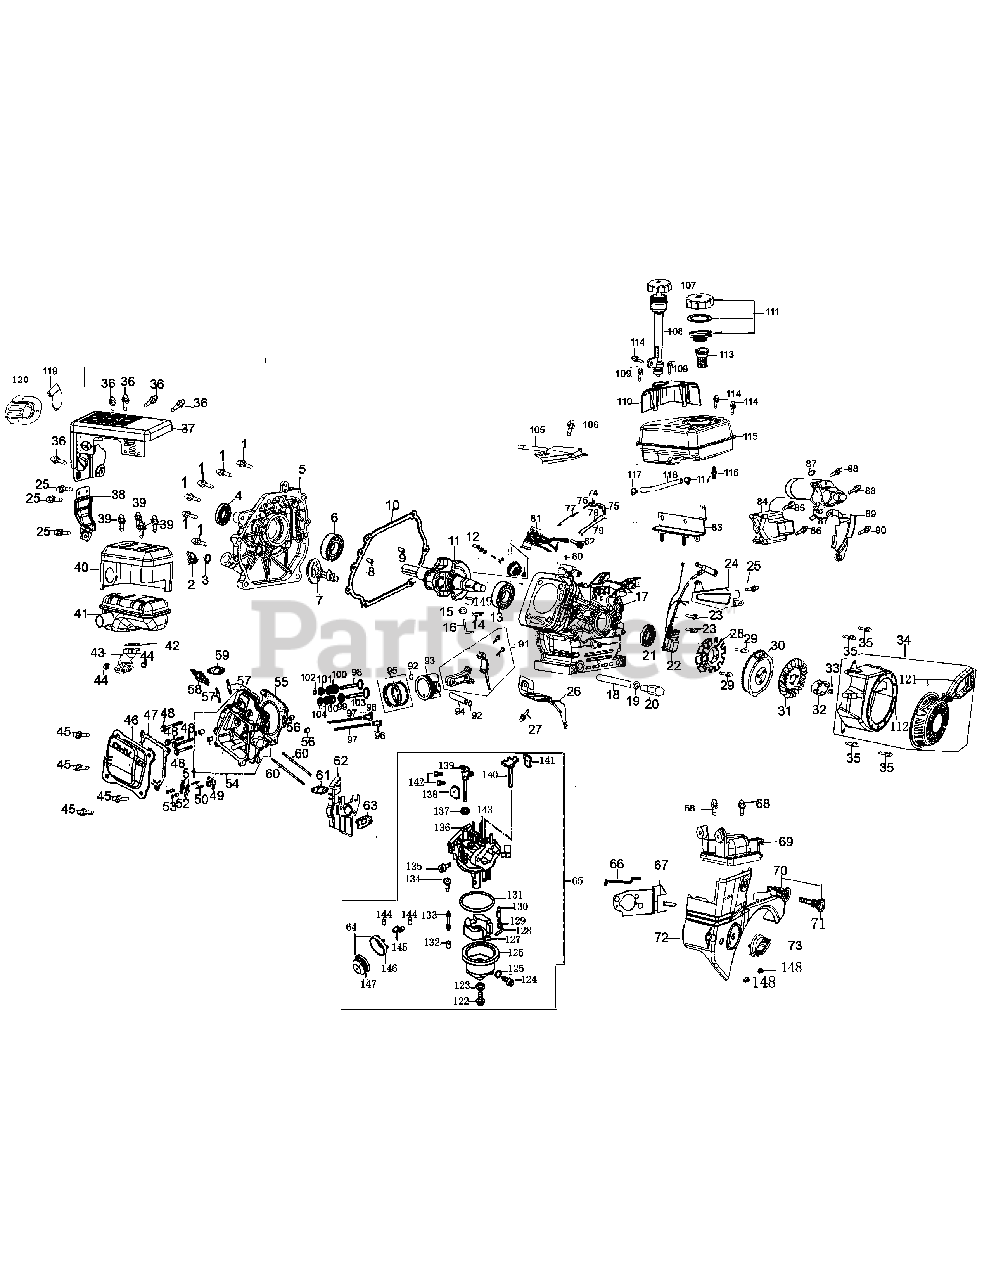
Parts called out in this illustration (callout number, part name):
1	Bolt
2	Oil Fill Plug Assembly
3	O-ring
5	Crankcase cover
6	Radial Ball Bearing
7	Camshaft Assembly
10	Crankcase Cover Gasket
11	Crankshaft Complete
12	Governor Kit
13	Radial Ball Bearing
14	Pin Lock
16	Governor Arm
17	Crankcase
18	Oil-Draining Pipe
18	Oil Drain Assembly
22	Ignition Module
28	Stator
31	Cooling Fan
32	Starter Cup
35	Recoil Bolt
37	Muffler Shroud
40	Muffler Shield
41	Muffler Complete
42	Gasket
47	Valve Cover Gasket
49	Plate Push Rod Guide
50	Pivot Bolt
51	Rocker Arm
52	Valve Adjusting Nut
53	Pivot Locking Nut
54	Cylinder Head Complete
55	Cylinder Head Gasket
57	Muffler Stud Assembly, 8 × 34
58	Spark Plug
59	Gasket Muffler
59	Gaske tMuffler
61	Insulator Gasket Carburetor
61	Carburetor Insulator Gasket
62	Insulator Carburetor
62	Carburetor Insulator
63	Carburetor Gasket
63	Gasket Carburetor
65	Carburetor Assembly
66	Choke Push Rod
69	Air Filter Heating Pipe Cover
70	Key Switch
71	Key
72	Shroud
73	Choke Knob
77	Spring Governor
78	Spring Throttle Return
79	Rod Governor
81	Throttle Control Assembly
82	Throttle Control Knob
84	Electric Starter, 110v
91	Connecting Rod Assembly
92	Piston Pin Clip
93	Piston
94	Pin Piston
97	Push Rod
97	Push Rod Kit
98	Exhaust Valve
98	Valve Kit
99	Valve Seal
100	Spring Valve
101	Exhaust Valve Spring Retainer
102	Exhaust Valve Adjuster
103	Intake Valve
104	Internal Valve Spring Retainer
107	Dipstick
108	Dipstick Base
110	Dipstick Decoration Cover
111	Fuel Tank Cap
112	Blower Housing
113	Fuel Filter
115	Fuel Tank
116	Nipple Fuel Tank
117	Fuel Line Kit
121	Recoil Starter Assembly
121	Starter Handle
122	Fuel Drain Plug
123	Fuel Cup Fixed Bolt Packing
124	Fuel Drain Plug
125	Fuel Drain Plug Gasket
126	Fuel Cup
127	Float
128	Floating Pin
129	Needle Valve Spring
130	Needle Valve
131	O-ring Packing
132	Main Jet
133	Main Nozzle
134	Idle Jet Assembly
135	Idle Speed Adjusting Screw
136	Carburetor Body
137	Fiber Seal
138	Choke Plate
139	Throttle Shaft
140	Choke Plate
141	Choke Shaft
142	Cross Screw
143	Position Spring
144	Clip
145	Fuel Hose
146	Primer Base
147	Primer Bulb
147	Primer
149	Woodruff Key
